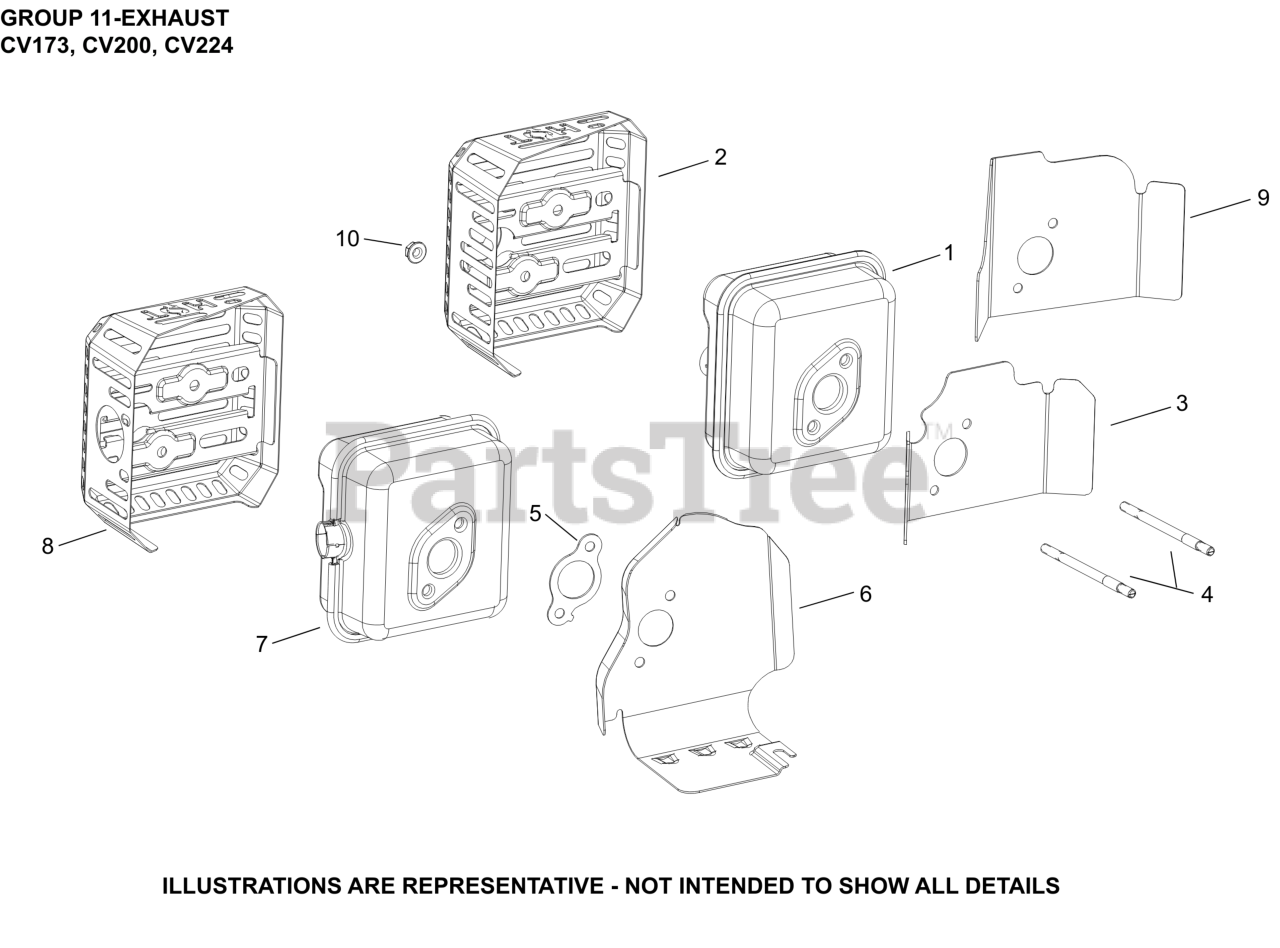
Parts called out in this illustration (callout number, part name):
1	MUFFLER, ASSEMBLY
2	GUARD, MUFFLER ASSEMBLY
4	STUD, EXHAUST (M6)
5	GASKET, MUFFLER (HEAT DEFLECTOR)
6	BAFFEL, BARREL
